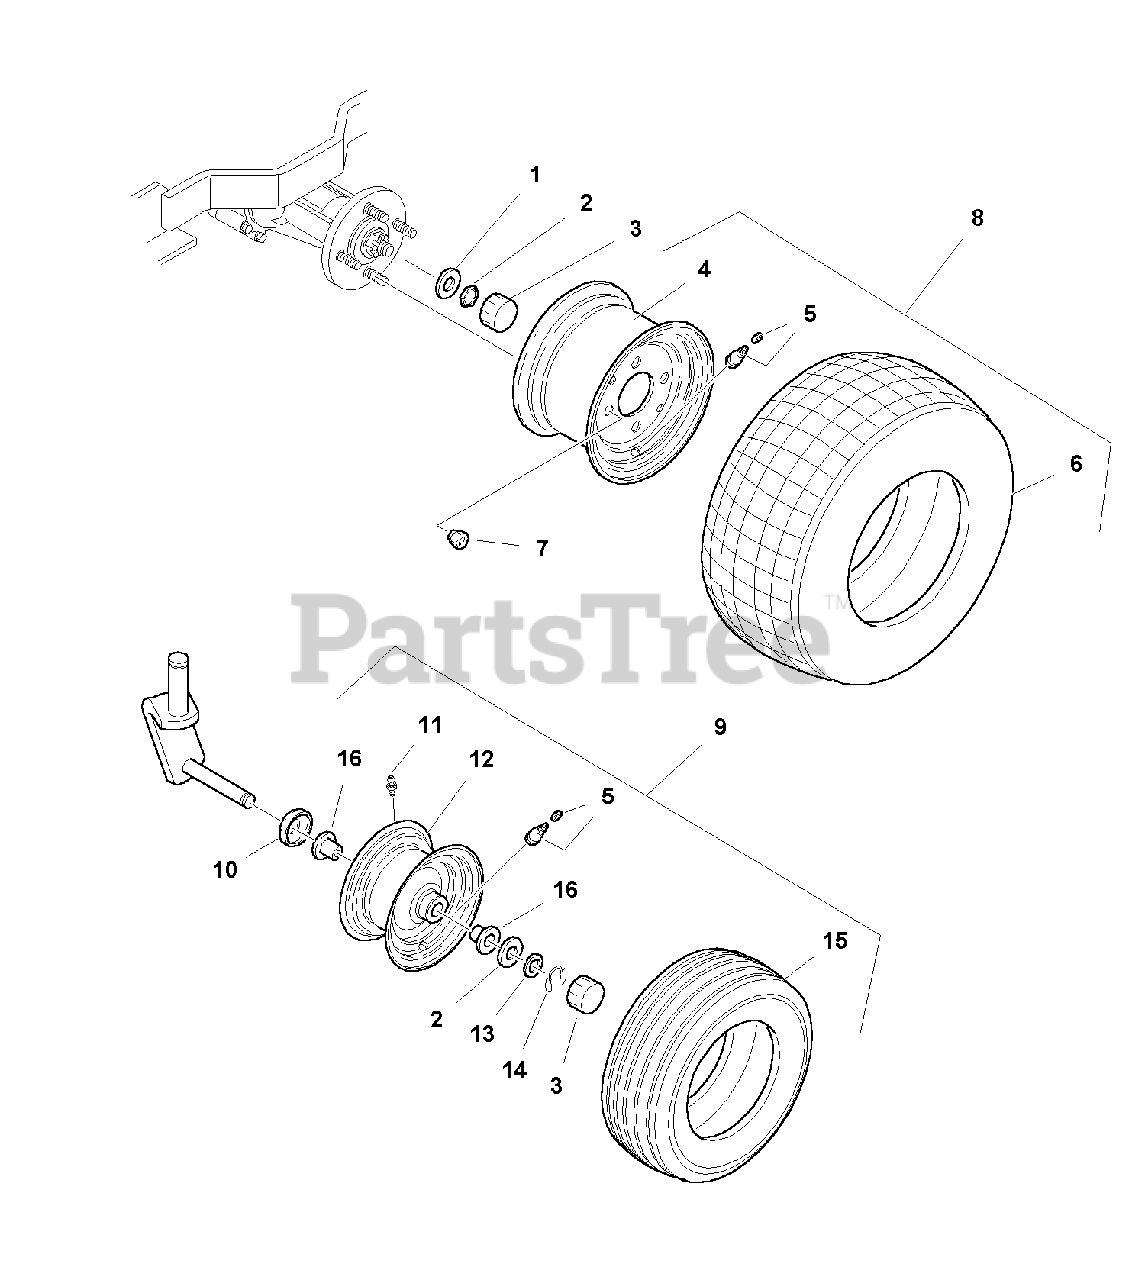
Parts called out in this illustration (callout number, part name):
2	NUT, Hex Lock Pal, 3/4-20
4	REAR WHEEL (14HP Models)
4	REAR WHEEL (16HP Models)
4	REAR WHEEL (18HP Models)
5	VALVE STEM & CAP
6	TIRE, 18 x 8.50-8, Turf Trac, R/S
6	TIRE, 18 x 9.50-8, Turf Trac, R/S
6	TIRE, 18 x 9.50-8, Turf 4 PLY
6	TIRE, 18 x 8.50-8, Turf 4 PLY
8	WHEEL & TIRE ASSEMBLY, Carlisle, Rear, 18 x 8.50-8 (14HP Models) (Includes Ref. Nos. 4, 5, 6, & 18)
8	WHEEL & TIRE ASSEMBLY, Rear, 18 x 8.50-8 (16 HP Models) (Includes Ref. Nos. 4, 5, 6, & 18)
8	WHEEL & TIRE ASSEMBLY, Rear, 18 x 9.50-8 (18HP Models) (Includes Ref. Nos. 4, 5, 6, & 18)
8	WHEEL & TIRE ASSEMBLY, Hoosier, Rear, 18 x 8.50-8 (16HP Models) (Includes Ref. Nos. 4, 5, 6, & 18)
8	WHEEL & TIRE ASSEMBLY, Hoosier, Rear, 18 x 9.50-8 (18HP Models) (Includes Ref. Nos. 4, 5, 6, & 18)
9	WHEEL & TIRE ASSEMBLY, Front, 13 x 5.00-6 (Includes Ref. Nos. 5, 11, 12, 15 & 16)
10	WASHER, Cupped
11	FITTING, Lube
12	FRONT WHEEL ASSEMBLY (Includes Ref. No. 11)
13	WASHER
14	RING, Klip, .750
15	TIRE, Front Rib Tread, 13 x 5.00-6
16	BUSHING, Wheel
